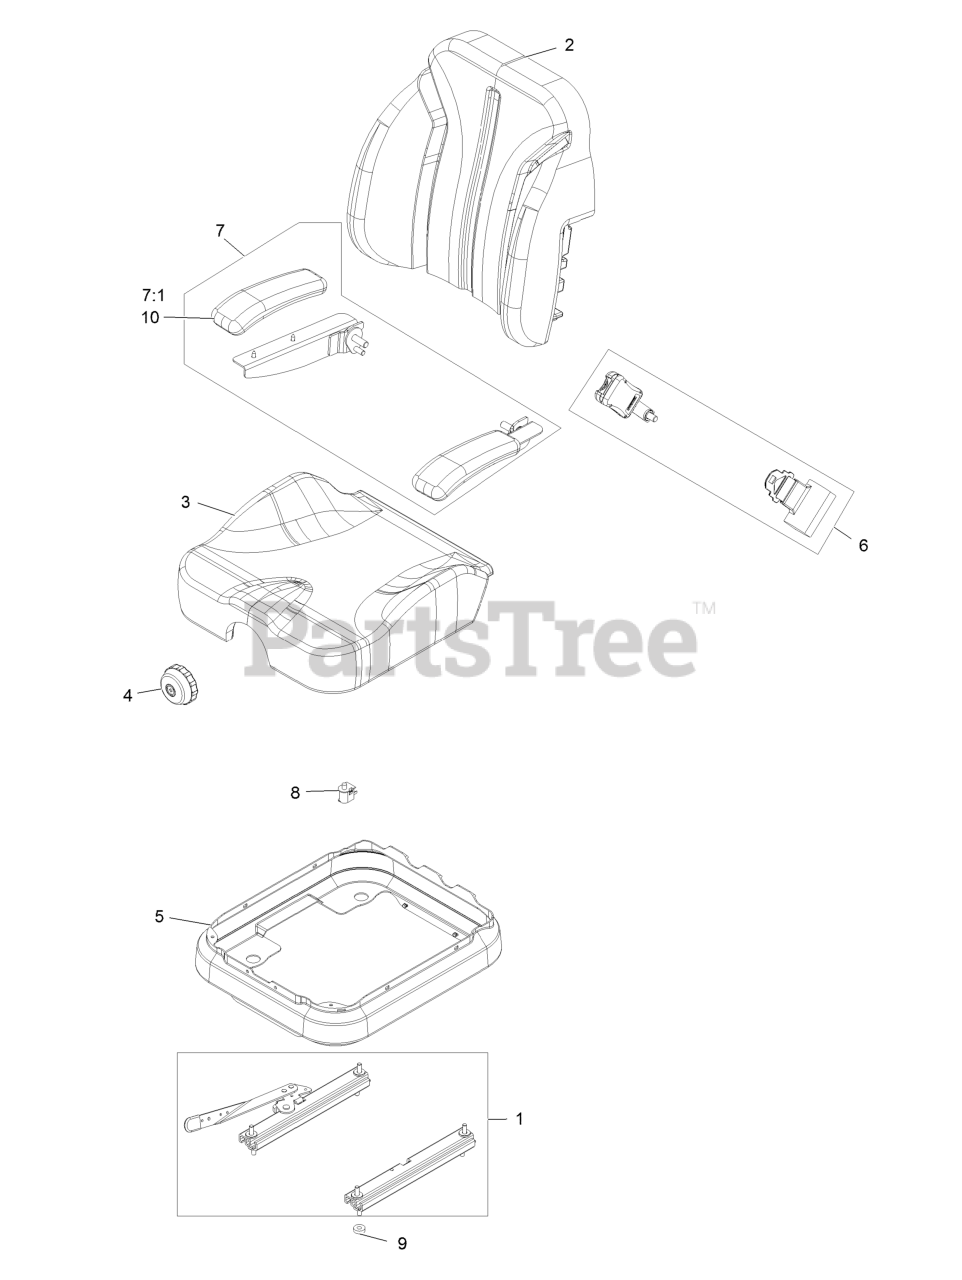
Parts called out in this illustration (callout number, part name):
1	Tracks-4" Travel
2	Cover-Seat Back Svc
3	Cover-Seat Bottom Svc
4	Knob-Adjuster
5	Bellows-Seat
6	Kit-Seat Belt
7	Armrest Kit
7:1	Cushion-Rest, Arm
9	Spacer-Pin, Mounting
10	Cushion-Rest, Arm
